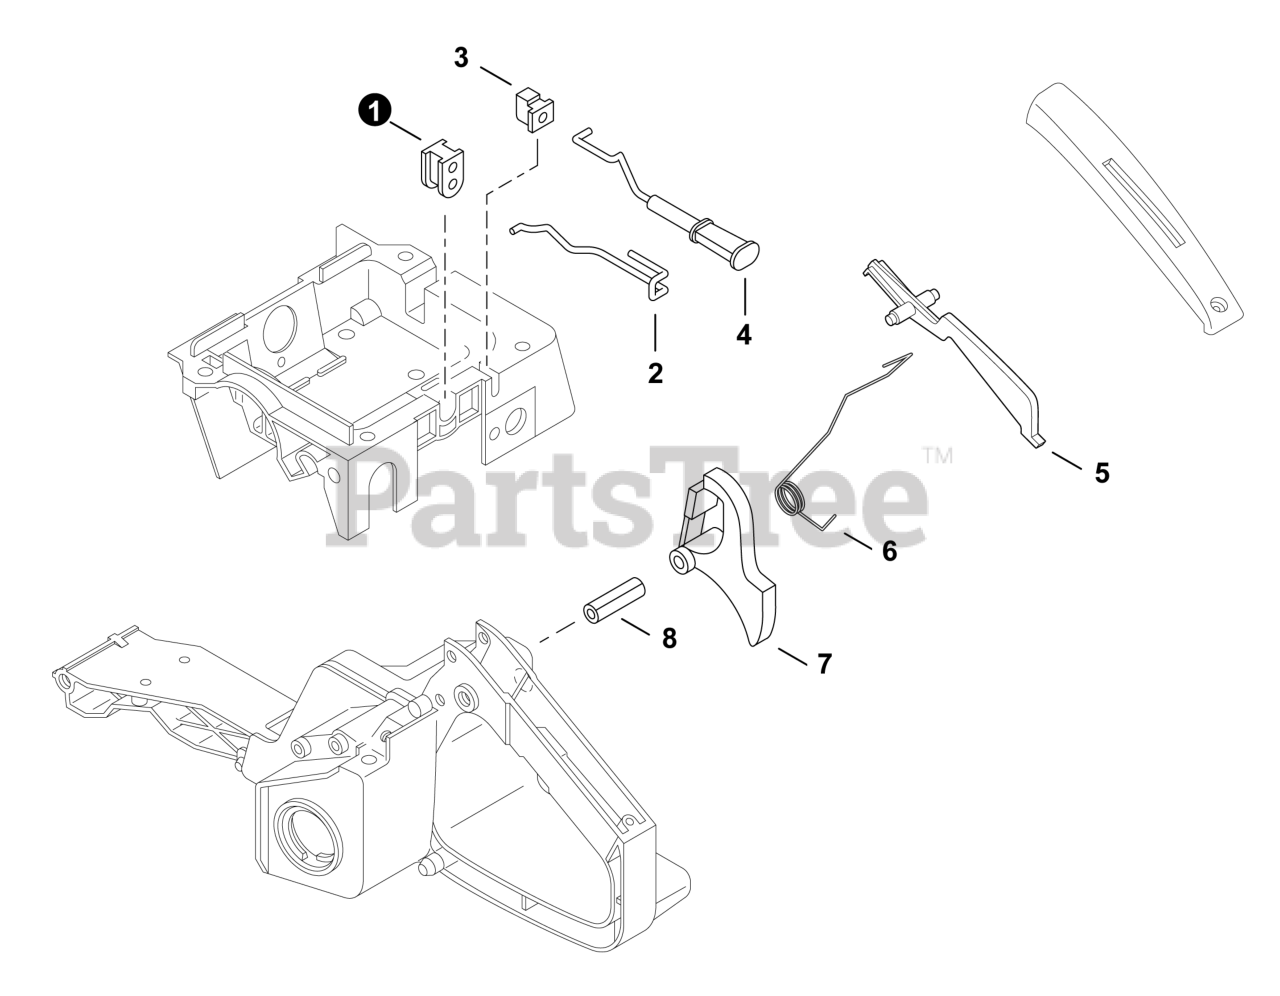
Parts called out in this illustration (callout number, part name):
1	GROMMET, THROTTLE ROD
2	ROD, THROTTLE
3	GROMMET, CHOKE
4	ROD, CHOKE
5	LEVER, THROTTLE LOCKOUT
6	SPRING, THROTTLE RETURN
7	TRIGGER, THROTTLE
8	PIN, SPRING Ø5×25 MM
